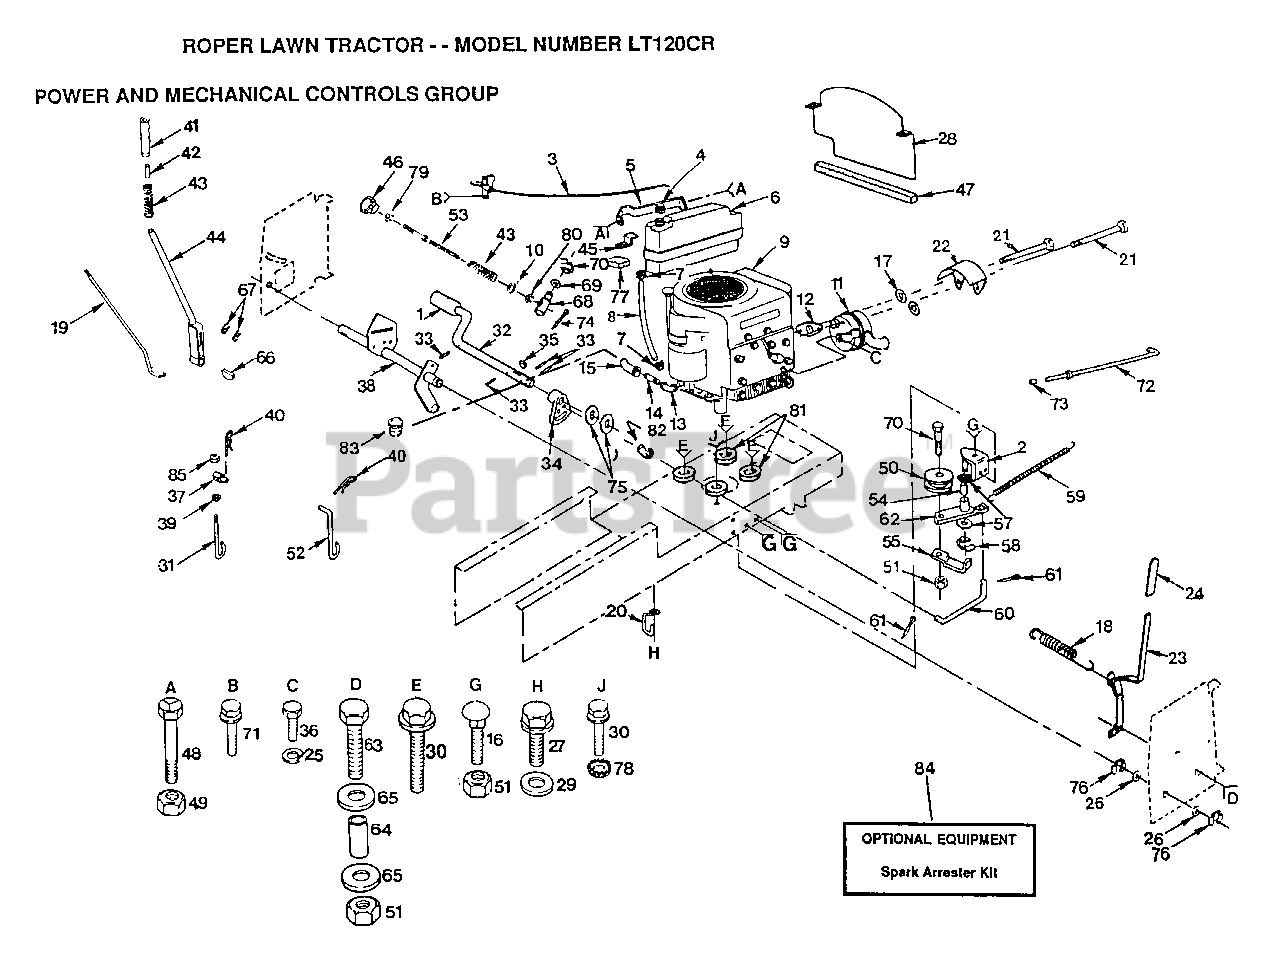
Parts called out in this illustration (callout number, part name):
1	PEDAL COVER T
5	SUPT TANK FUEL
6	FUEL TANK
8	HOSE T
9	ENGINE 12 H.P. TYPE 0201-01
10	WASHER
11	MUFFLER
13	STREET ELBOW LT
14	PIPE NIPPLE
15	ELBOW
16	BOLT
18	"SPRING.EXT.8.5"""
19	ROD ASSY-LEVER LT
21	BOLT
22	HEAT SHIELD
25	LOCKWASHER
26	WASHER
27	SCREW
29	WASHER
30	SCREW LT
31	PIVOT PIN T
32	FOOT SHAFT PEDAL
34	ARM BRAKE LT
36	BOLT
39	NUT
41	GRIP
43	SPRING T
44	LEVER ASSY LT
45	BRACE-TANK LT
46	HDLE ADJ LIFT
48	BOLT
52	LIFT LINK LT
53	ROD LIFT LT
54	"LY, BEARING"
57	WASHER LT
58	KLIP RING
59	"SPRING, RETURN LT"
60	"LINK, CLUTCH T"
61	COTTER PIN
65	WASHER GT
69	WASHER
70	KLIP RING
71	SCREW
73	PLUNGER CAP T
75	WASHER
76	E-RING
77	PAD-SPACER T
78	LOCKWASHER
79	NUT
80	NUT T
82	STREET ELBOW LT
83	PLUG T
84	SPARK ARREST KIT
